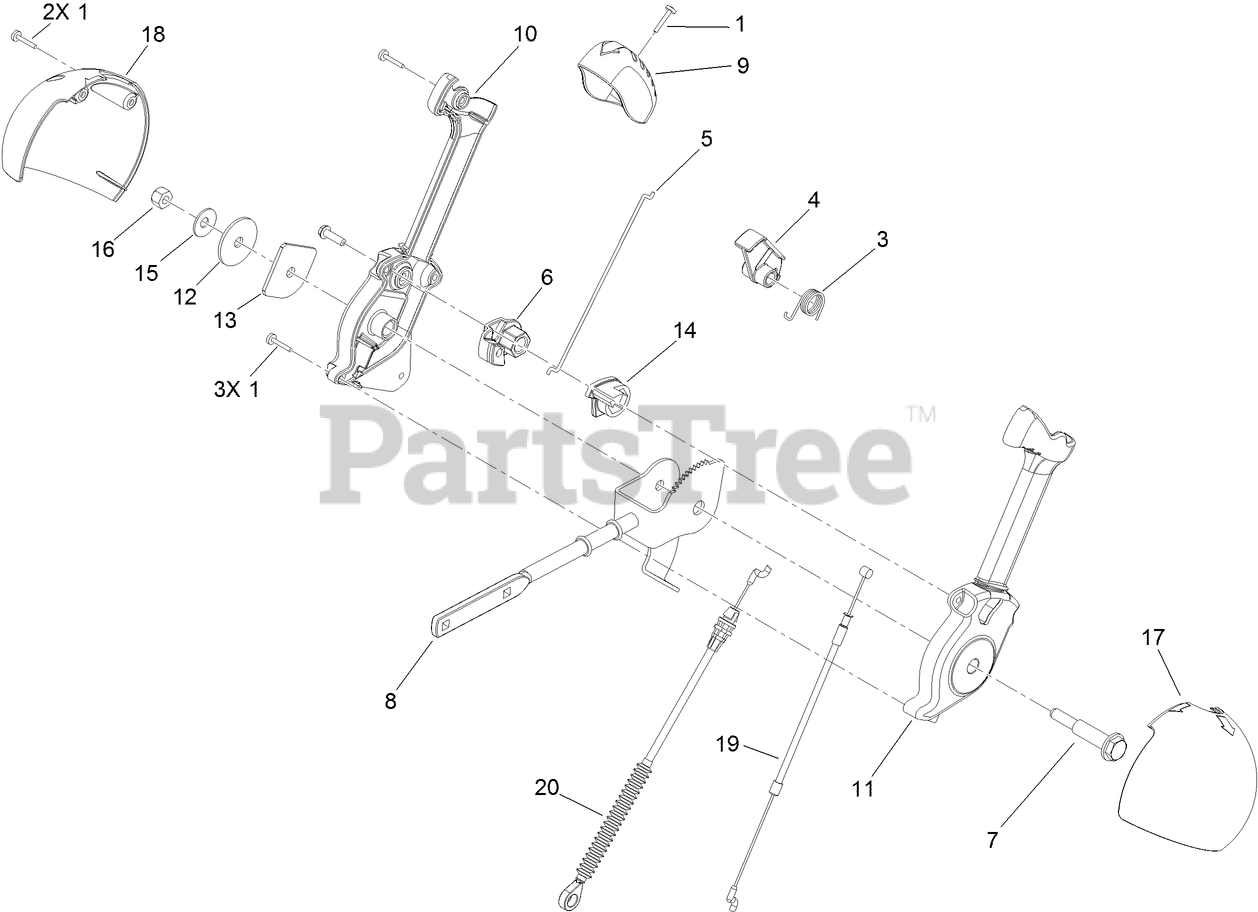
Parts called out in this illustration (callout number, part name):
1	SCREW-PPH
3	SPRING-TORSION
4	TRIGGER-LATCH
5	LINK-LATCH
6	LEVER-CABLE, DEFLECTOR
7	SCREW-SHOULDER
9	CAP-LEVER
10	LEVER-CONTROL, CHUTE (RH)
11	LEVER-CONTROL, CHUTE (LH)
12	WASHER-NYLON
14	PAWL-LATCH
15	WASHER-BELLEVILLE
16	NUT-LOCK, NI
17	COVER-LEVER, CHUTE (LH)
18	COVER-LEVER, CHUTE (RH)
19	CABLE-RELEASE, CHUTE
20	CABLE-CONTROL, DEFLECTOR
